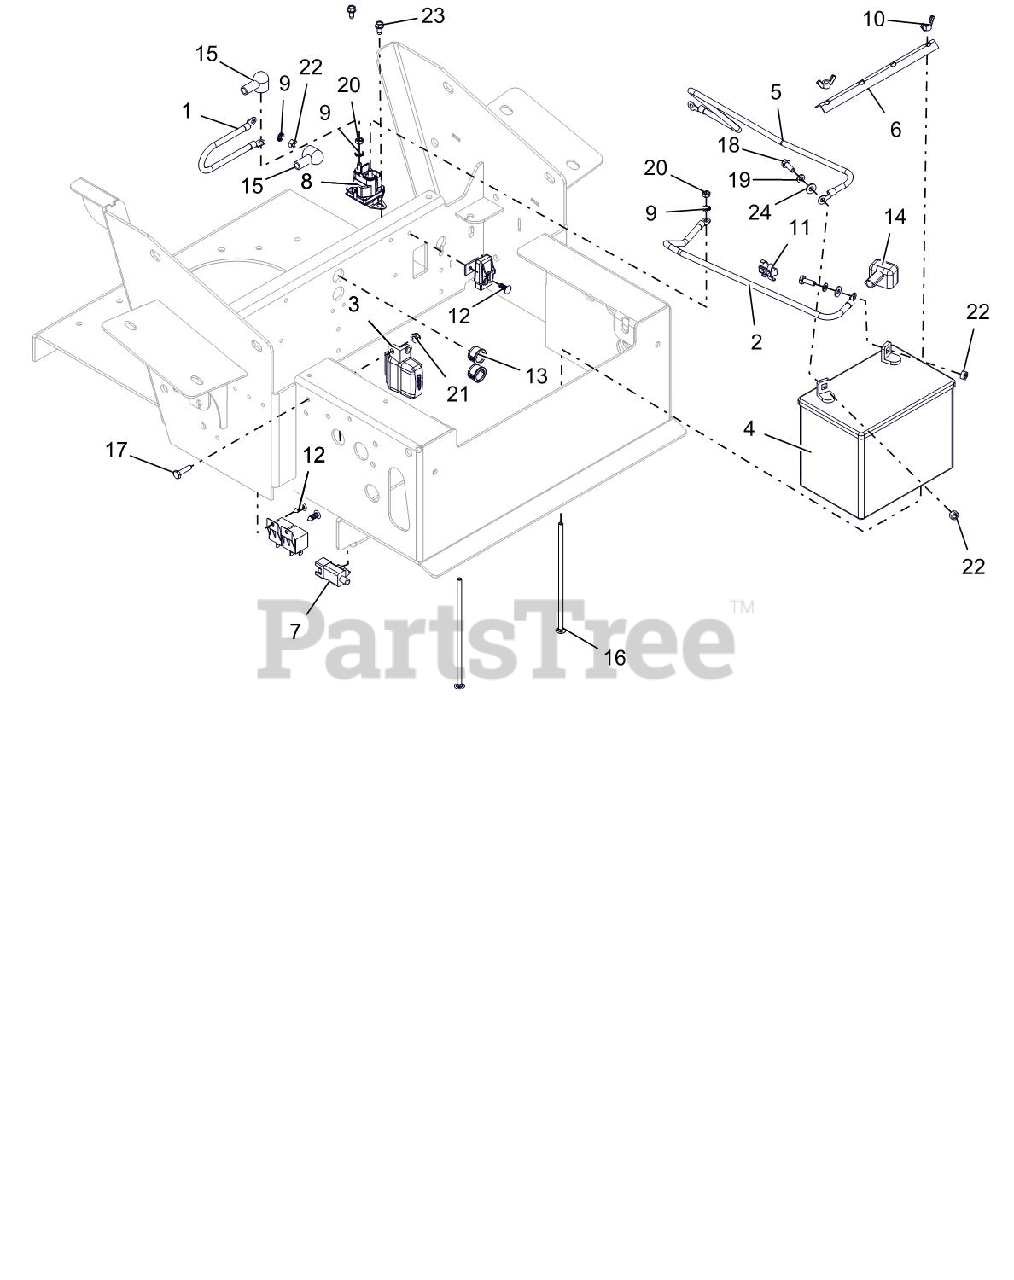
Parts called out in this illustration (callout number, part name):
1	CABLE, POS W/(2)1/4 RING 9.0LG
2	CABLE,POS W/(2)1/4 RING 21.5LG
3	HARNESS, PT WIRE
3	RELAY,SEALED W/DIODE
3	DIODE, CONNECTOR SHELL
3	FUSE, 5 AMP MINI-ATC
3	FUSE-10 AMP ATC TYPE
3	FUSE,20 AMP MINI ATC
3	FUSE, 20 AMP BLADE S/O
4	BATTERY, 300 CCA 10U1L
5	CABLE-NEGATIVE BATTERY 24.00"
6	HOLD DOWN
7	SWITCH, SNAP IN - N.O./N.O.
8	SOLENOID, STARTER (SEALED)
9	@WSHR-LK-EXT.262X.502X.026YWZC
10	NUT-LK WING .250-20 YWZC
11	CLIP,T,.31-.38,
12	RIVET, .25 NYLON PANEL
13	BUSH, PANEL SNAP .687X.875X.56
14	INSULATOR
15	BOOT, EYELET TERMINAL
16	BLT-RDHDSQNK .25-20X7.50 GR2YZ
17	@BLT-HEX .25-20X1.00 GR5 YWZC
18	@BLT-HEX .25-20X.75 GR5 YWZC
19	@WSHR-LK .25X.062 REG YWZC
20	NUT-HEX M6X1.0 YWZC
21	@NUT-LK-NYL-FLG .25-20 YWZC
22	@NUT-HEX .25-20 YWZC
23	SCR-TAP .25-20X.50 HWH TR YWZ
24	@WSHR-FL-STL.281X.62X.065 YWZC
